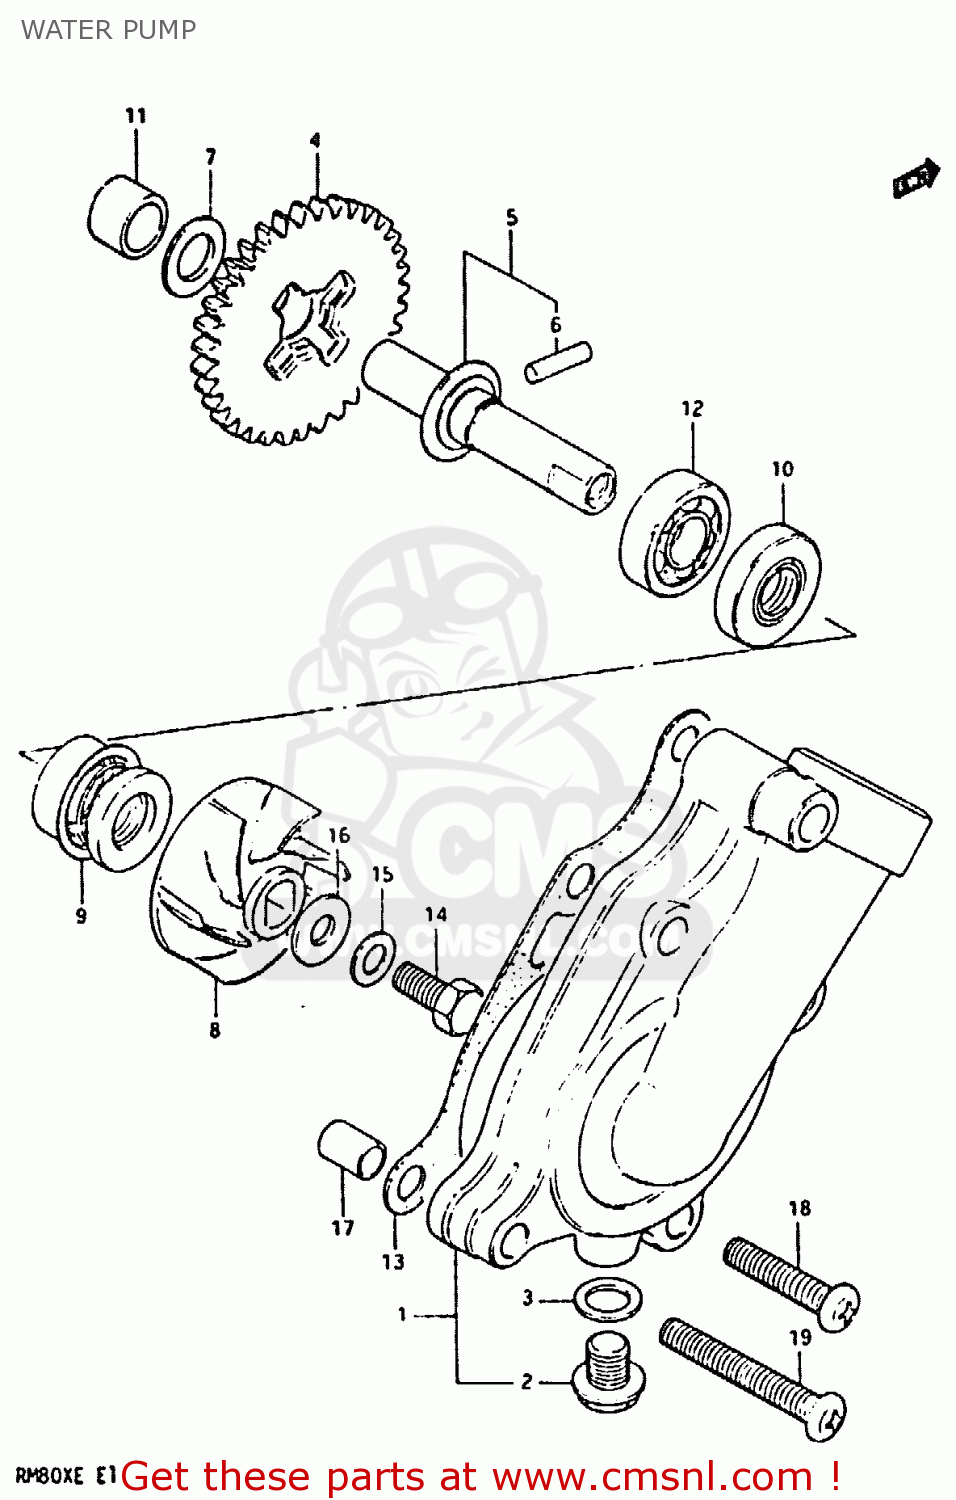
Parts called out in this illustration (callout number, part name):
1	CASE,WATER PUMP
2	BOLT,DRAIN
3	GASKET,DRAIN (NAS)
4	GEAR, DRIVEN (NT:35)
5	SHAFT,WATER PUMP
6	PIN (4X20.8)
7	WASHER,THRUST
8	IMPELLER,WATER PUMP
9	SEAL,WATER PUMP SHAFT
10	SEAL,OIL(10X21X5)
11	BUSH
12	BEARING
13	GASKET,WATER PUMP CASE (MCA)
14	BOLT(6X13)
15	WASHER
16	GASKET (NAS)
17	PIN
18	SCREW
19	SCREW
